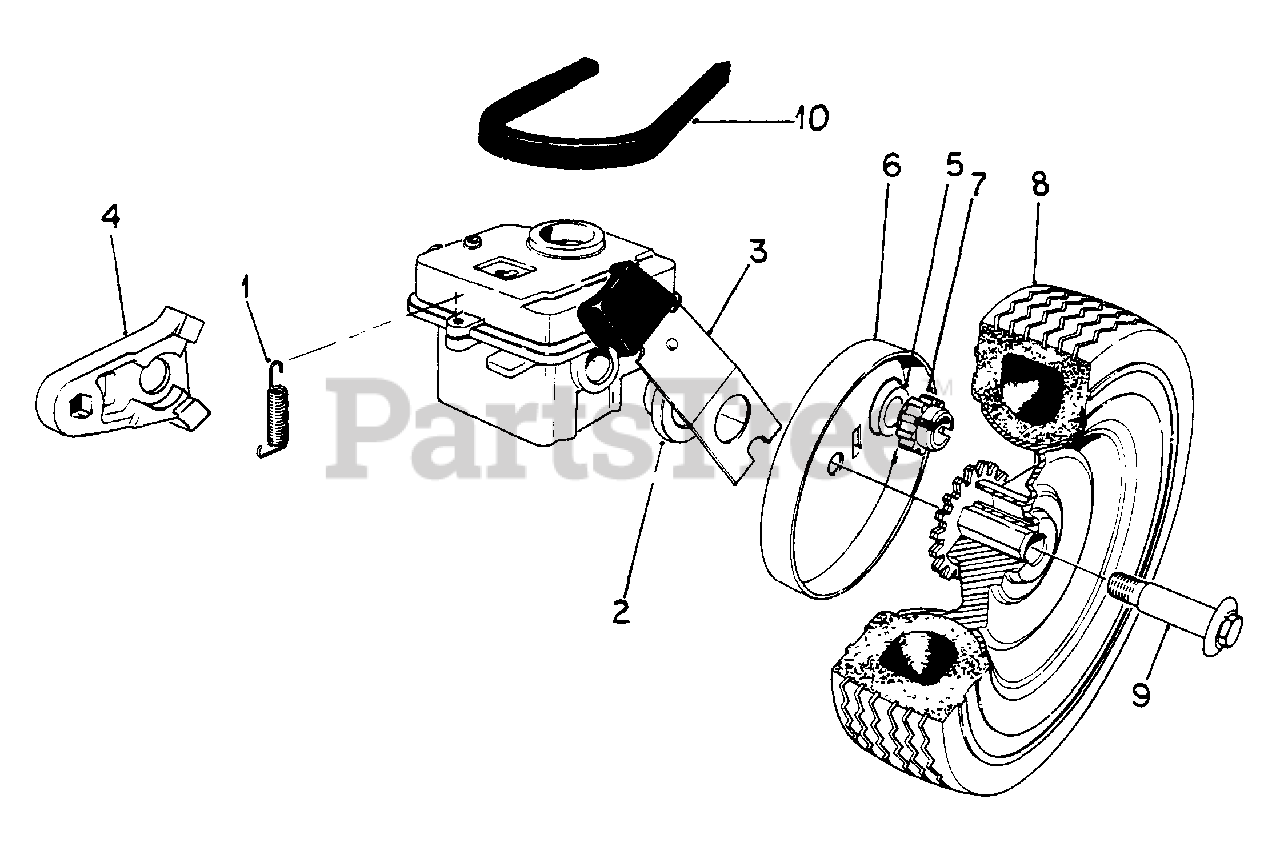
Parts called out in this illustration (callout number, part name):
1	SPRING, BELT TENSION
3	ARM, SPRING LH
3	ARM, SPRING RH
5	WASHER, THRUST
6	COVER, WHEEL
7	GEAR, PINION
8	WHEEL W/TIRE, FRONT
9	BOLT, WHEEL
10	BELT, DRIVE
